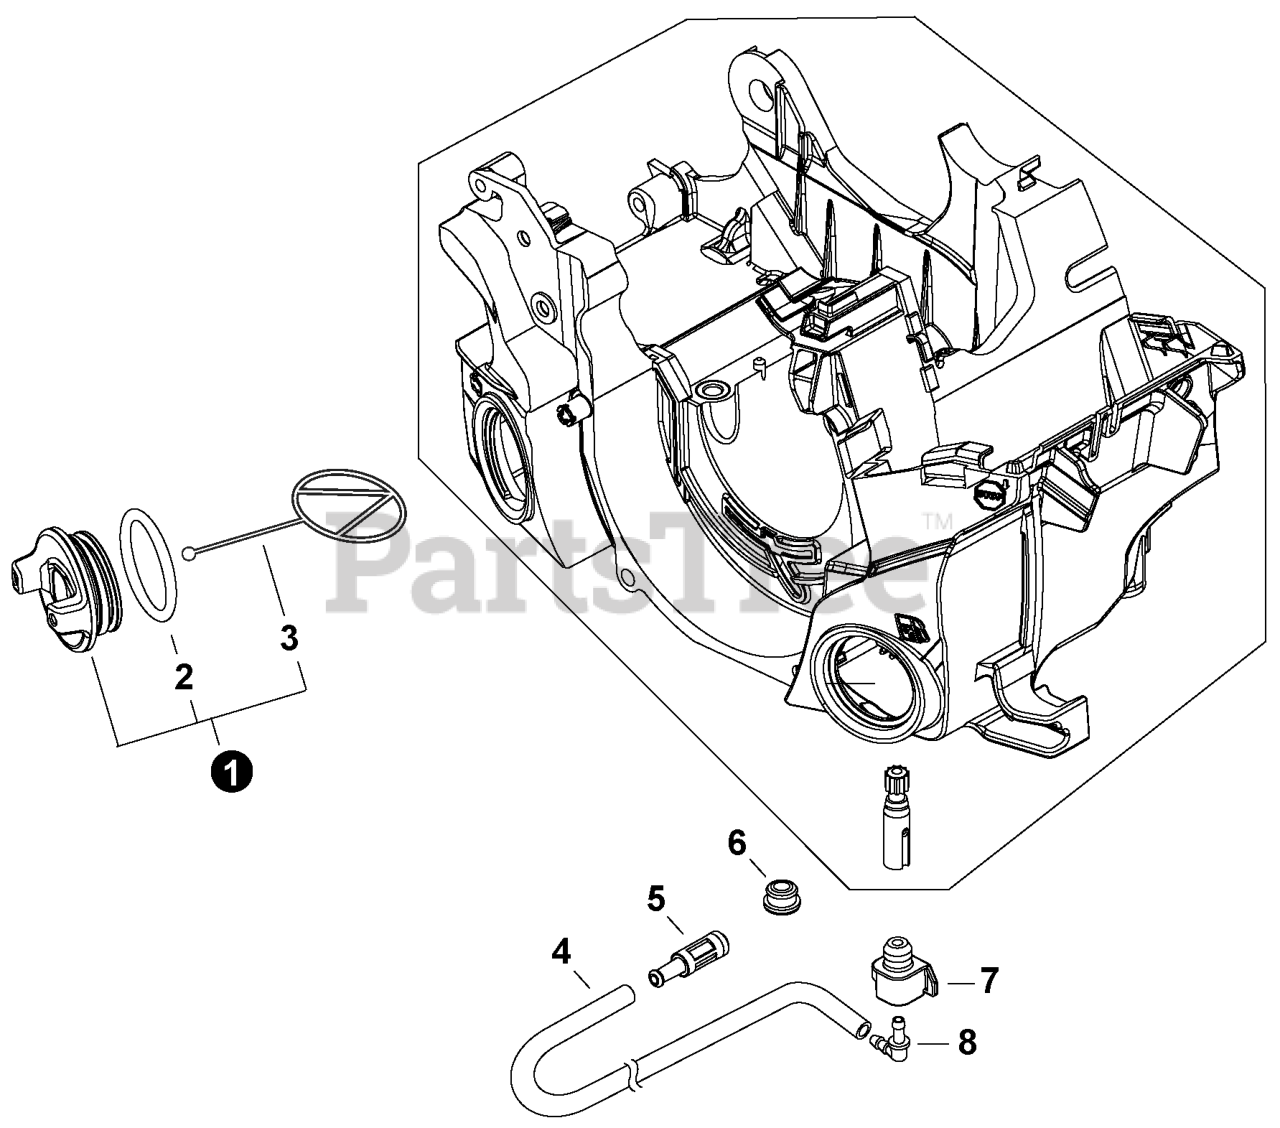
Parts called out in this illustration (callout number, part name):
1	CAP ASSY, OIL
2	O-RING 29
3	CONNECTOR, CAP L= 60 MM
4	PIPE 3x6x210 BLACK
5	FILTER, OIL
7	GROMMET, OIL
8	CONNECTOR, PIPE
